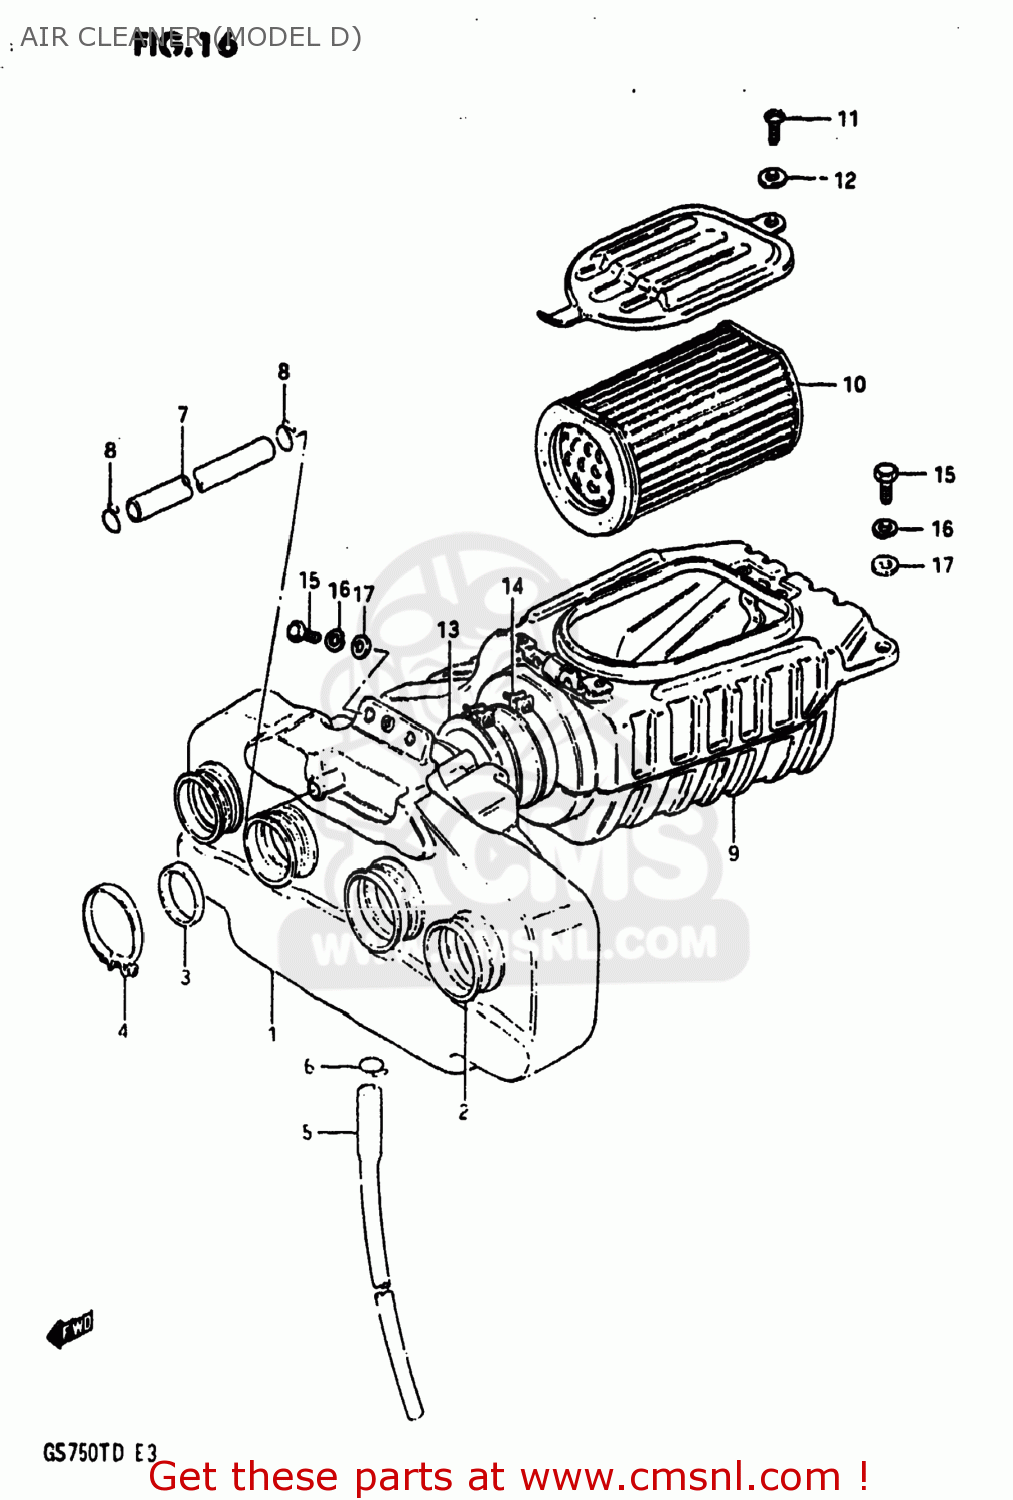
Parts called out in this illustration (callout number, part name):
1	CASE COMP,AIR CLEANER
2	TUBE,OUTLET
3	RING
4	CLAMP
5	DRAIN TUBE
6	CLIP
7	TUBE,BREATHER
8	CLIP
9	CLEANER SET,AIR,REAR
10	FILTER,AIR CLEANER
11	SCREW
12	WASHER
13	HOSE,AIR CLEANER
14	BAND
15	BOLT
16	LOCK WASHER
17	WASHER
